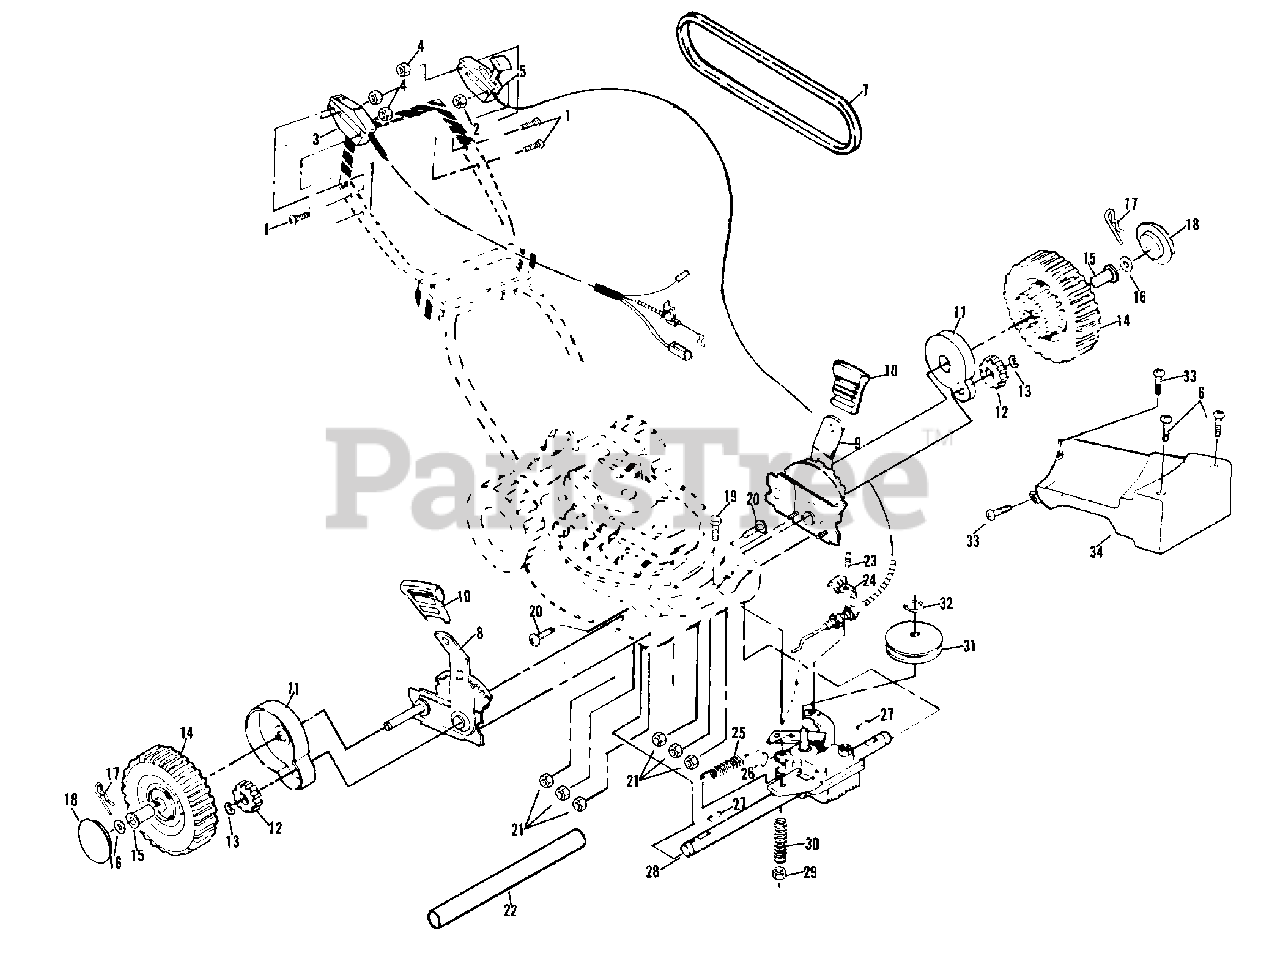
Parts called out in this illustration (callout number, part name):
1	Machine Screw 1/4-20 x 2-1/8
2	Locknut 1/4-20
3	Engine Zone Control Cable
4	Locknut 1/4-20
5	Drive Control
6	Self-tapping Screw #10-24 x 2-3/4
8	Wheel Adjuster Assembly (Right)
9	Wheel Adjuster Assembly (Left)
10	Selector Knob
11	Dust Cover
13	E-Ring
14	Wheel & Tire Assembly 8.0 x 2.0
15	Wheel Bushing
17	Retainer Clip
19	Hex Head Bolt 1/4-20 x 2-3/4
20	Flat Head Machine Screw 1/4-20 x 3/4
21	Locknut 1/4-20
22	Drive Shaft Cover
23	Hex Washer Head Tapping Screw #10-24 x 3/8
24	Cable Clamp
26	Woodruff Key #213
27	Woodruff Key #3
28	Gear Case Assembly
29	Locknut
30	Spring
31	Drive Pulley
32	Retaining Ring
33	Hex Washer Head Screw #10-24 x 1/2
34	Drive Cover
